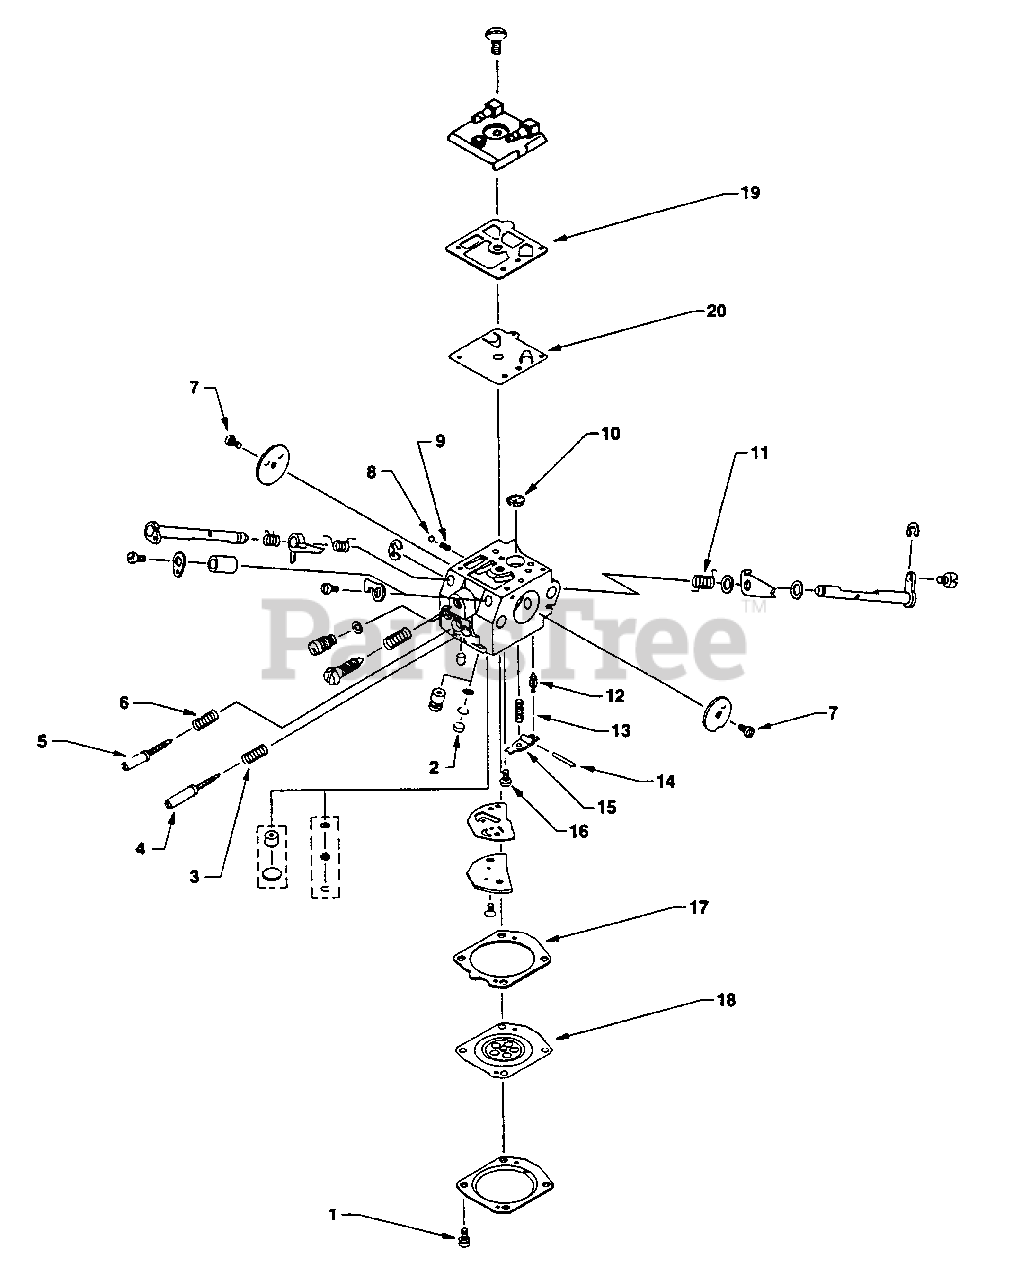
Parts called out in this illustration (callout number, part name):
1	Repair Kit
2	Repair Kit
3	Repair Kit
4	Repair Kit
5	Repair Kit
6	Repair Kit
7	Repair Kit
8	Repair Kit
9	Repair Kit
10	Repair Kit
11	Repair Kit
12	Repair Kit
13	Repair Kit
14	Repair Kit
15	Repair Kit
16	Repair Kit
17	Repair Kit
18	Repair Kit
19	Repair Kit
20	Repair Kit
